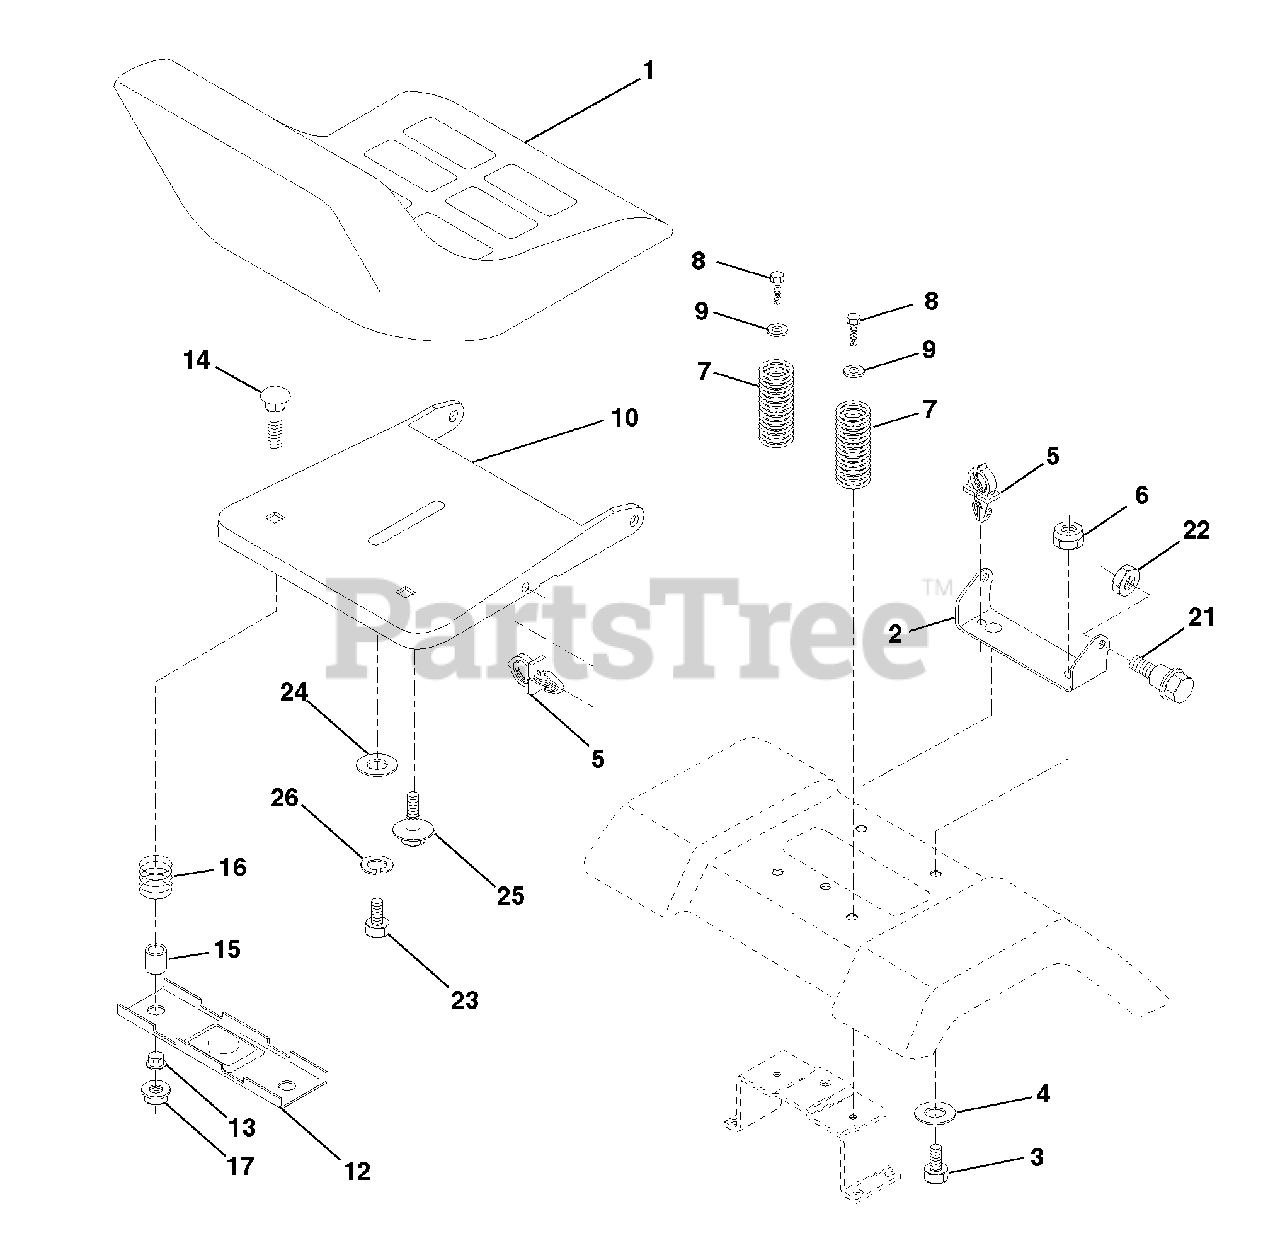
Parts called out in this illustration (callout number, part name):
1	Seat
2	Bracket Pivot Seat 8 720
3	Bolt Fin Hex 3/8-16unc X 1
4	Washer 13/32 X 1 X 10 Ga
5	Clip Push-In
6	Nut Hex w/Ins. 3/8-16 Unc
7	Spring Seat Cprsn 2 250 Blk Zi
8	Screw Thdrol 3/8-16 X 1 Ty-tt
9	Washer 13/32 X 1 X 14 Ga.
10	Pan Seat
12	Bracket Mounting Switch
13	Bushing Snap Blk Nyl 50 Id
14	Bolt Rdhd Sqnk 1/4-20 x 1-1/2
15	Spacer Split 28 x 96 Yel Zinc
16	Spring Cprsn 1 27 Blk Pnt
17	Nut Lock 1/4 Lge Flg Gr 5 Zinc
21	Bolt Shoulder 5/16-18 Unc
22	Nut Hex Lock W/Ins 5/16-18
23	Bolt, Hex Head, Fin 1/2-13 x 7/8 Grade 5
24	Washer 17/32 X 1-3/16 X 12 Ga.
25	Bolt Shoulder 5/16-18 X 62
26	Washer Lock
